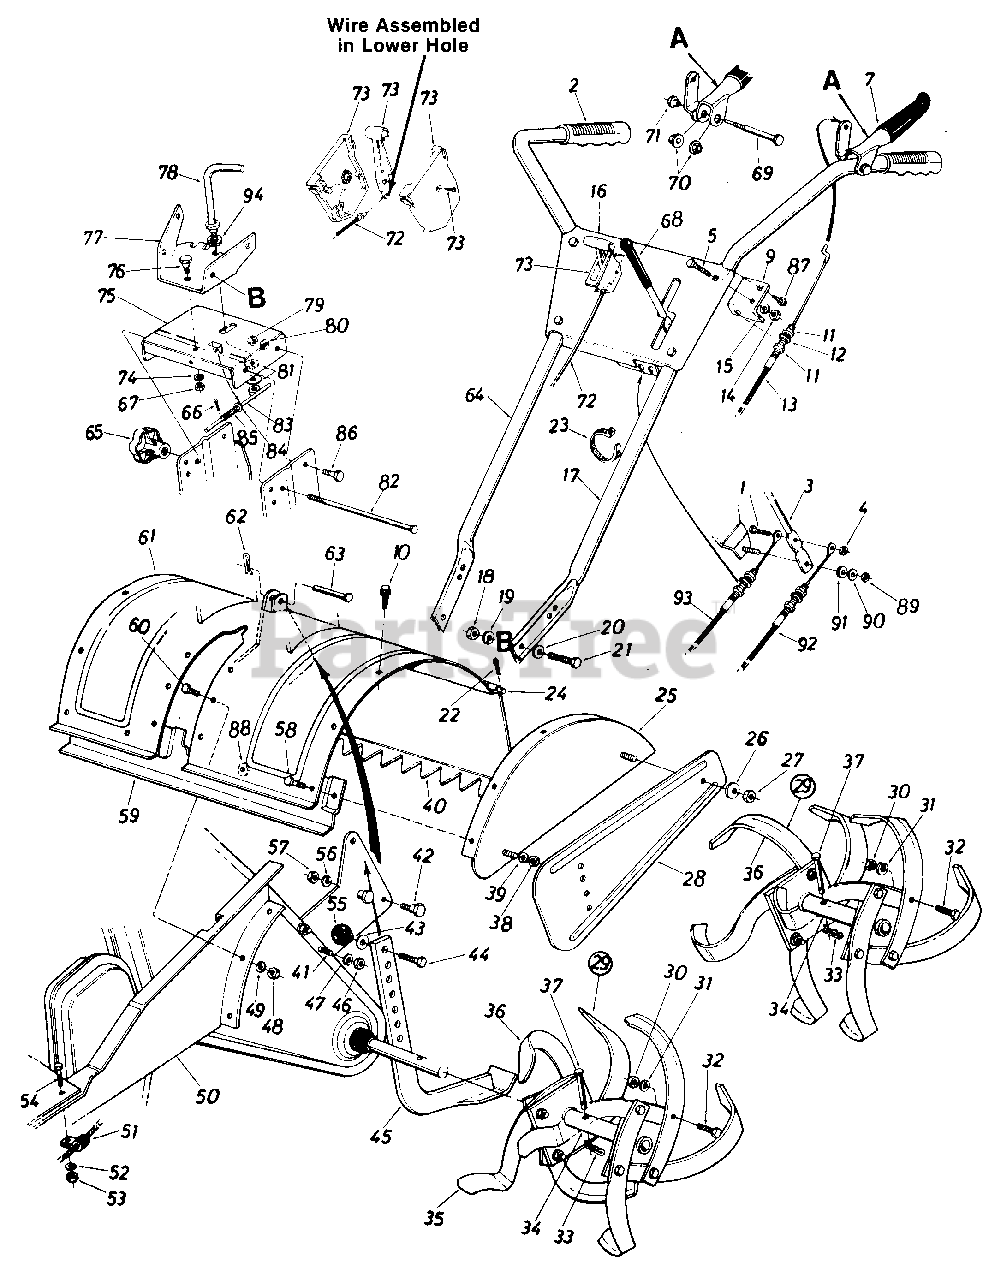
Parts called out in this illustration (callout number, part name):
1	Hex Bolt 1/4-28 x 1.0" Lg.*
2	Grip
3	Clutch Lever
4	Hex Cent. L-Nut 1/4-28 Thd.
5	Carr. Bolt 5/16-18 x 1.75"*
7	Clutch Grip Ass'y. L.H.
9	Clutch Cable Bracket
10	Hex Wash. S-Tap Scr. 5/16-18 x .62" Lg.
11	Hex Nut 5/16-24 Thd.
12	L-Wash. 5/16" I.D.*
13	Clutch Control Cable
14	Hex Nut 5/16-18 Thd.*
15	L-Wash. 5/16" I.D.*
16	Handle Panel Ass'y.
18	Hex Nut 3/8-16 Thd.*
19	L-Wash. 3/8" I.D.*
20	Bell-Wash. 3/8" I.D.
21	Hex Bolt 3/8-16 x 1.00" Lg.*
22	Cotter Pin 3/32" Dia. x 3/4"*
24	Tiller Flap Rod
27	Hex Nut 5/16-18 Thd.*
31	L-Wash. 3/8" I.D.*
32	Hex Bolt 3/8-24 x 1.25" Lg.*
33	Hairpin Cotter
38	Hex Nut 5/16-18 Thd.*
39	L-Wash. 5/16" I.D.*
41	Hex Bolt 5/16-18 x 1.0" Lg.*
42	Shld. Bolt 1/2" Dia. x .426"
43	Fl-Wash. 3/8" I.D. x 5/8" O.D.
44	Hex Bolt 3/8-16 x 3/4" Lg.*
46	Hex Nut 5/16-18 Thd.*
47	L-Wash. 5/16" I.D.*
48	Hex Nut 5/16-18 Thd.*
49	L-Wash. 5/16" I.D.*
52	L-Wash. 5/16" I.D.*
53	Hex Nut 5/16-18 Thd.*
54	Hex Bolt 5/16-18 x 3/4" Lg.*
55	Ball Knob 1/4" Dia.
56	L-Wash. 3/8" I.D.*
57	Hex Nut 3/8-16 Thd.*
58	Hex Bolt 5/16-18 x .75" Lg.*
63	Clevis Pin 3/8" Dia.
66	Cotter Pin 1/16" Dia. x .75"*
67	Hex Cent. L-Nut 3/8-16 Thd.
69	Shoulder Bolt .375" Dia. x 1.37" Lg.
70	Hex Flange Plastic Bearing
71	Shoulder Nut 1/4-20 Thd.
72	Throttle Control Wire
73	Throttle Control Box Ass'y.
74	Bell-Wash. .40" I.D. x 1.13"
79	Hex Cent. L-Nut 3/8-16 Thd.
80	Bell-Wash. .40" I.D. x .88"
81	Bell-Wash. 1/2" I.D. x 1.00"
82	Lock Pin 5/16" Dia. x 8"
83	Lower Sliding Ass'y.
84	Fl-Wash. .291" I.D. x .62"
85	Compression Spring .36" O.D. x 1.00" Lg.
86	Shoulder Bolt 1/2" Dia. x .170" Lg.
87	Hex Wash. S-Tap Scr. 1/4-20 x.50" Lg.
88	Bell-Wash. 5/16" I.D.
89	Hex Cent. L-Nut 5/16-18 Thd.
90	Fl-Wash. .344" I.D. x .87"
91	Rubber Wash. .33 I.D. x .87 "
92	Control Cable
93	Control Cable
94	Fl-Wash. .62" I.D. x 1.57"
14979-0638	SHIELD-REAR TINE - MTD/TROY-BILT RED (0638)
15390-0498	SHIELD-SIDE - OLD CUB YELLOW (0498)
15390-0499	SHIELD-SIDE - CUB BEIGE (0499)
15390-0629	SHIELD-SIDE - SILVER FLAKE (0629)
15390-0637	SHIELD-SIDE - POWDER BLACK (0637)
15390-0638	SHIELD-SIDE - MTD/TROY-BILT RED (0638)
15390-0648	SHIELD-SIDE - TECH GRAY (0648)
15390-0662	SHIELD-SIDE - OYSTER GRAY (0662)
15390-0665	SHIELD-SIDE - YARDMAN GREEN (0665)
15390-0674	SHIELD-SIDE - YARDMAN YELLOW (0674)
